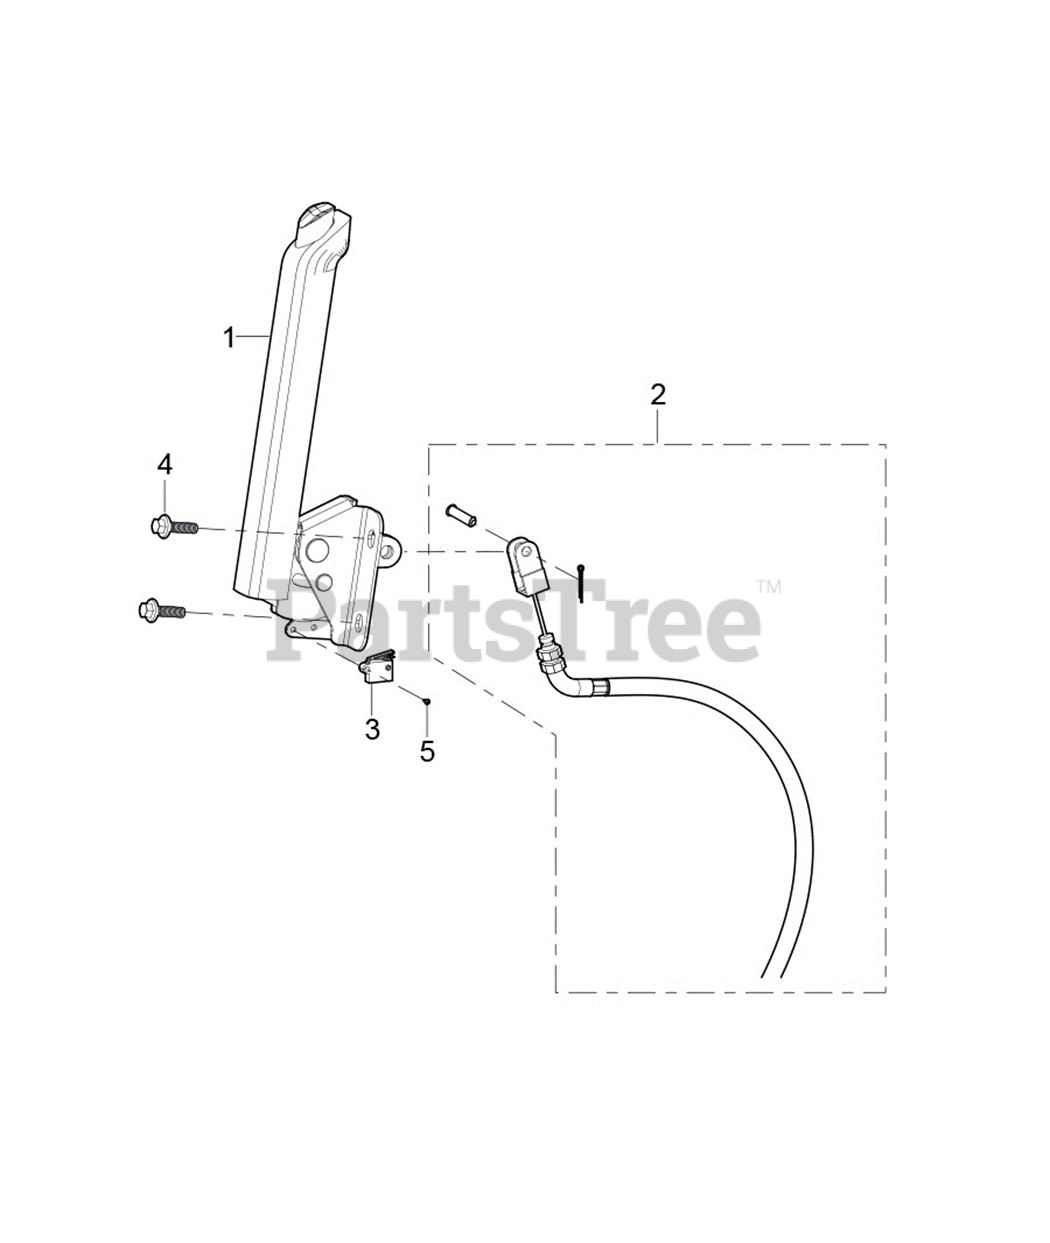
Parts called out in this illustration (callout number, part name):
1	PARKING BRAKE ASSEMBLY
2	PARKING BRAKE CABLE
3	PARKING BRAKE SWITCH
4	CROSS PLATE HEAD SCREW M8X16
5	CROSS HEAD SCREW M3X12
